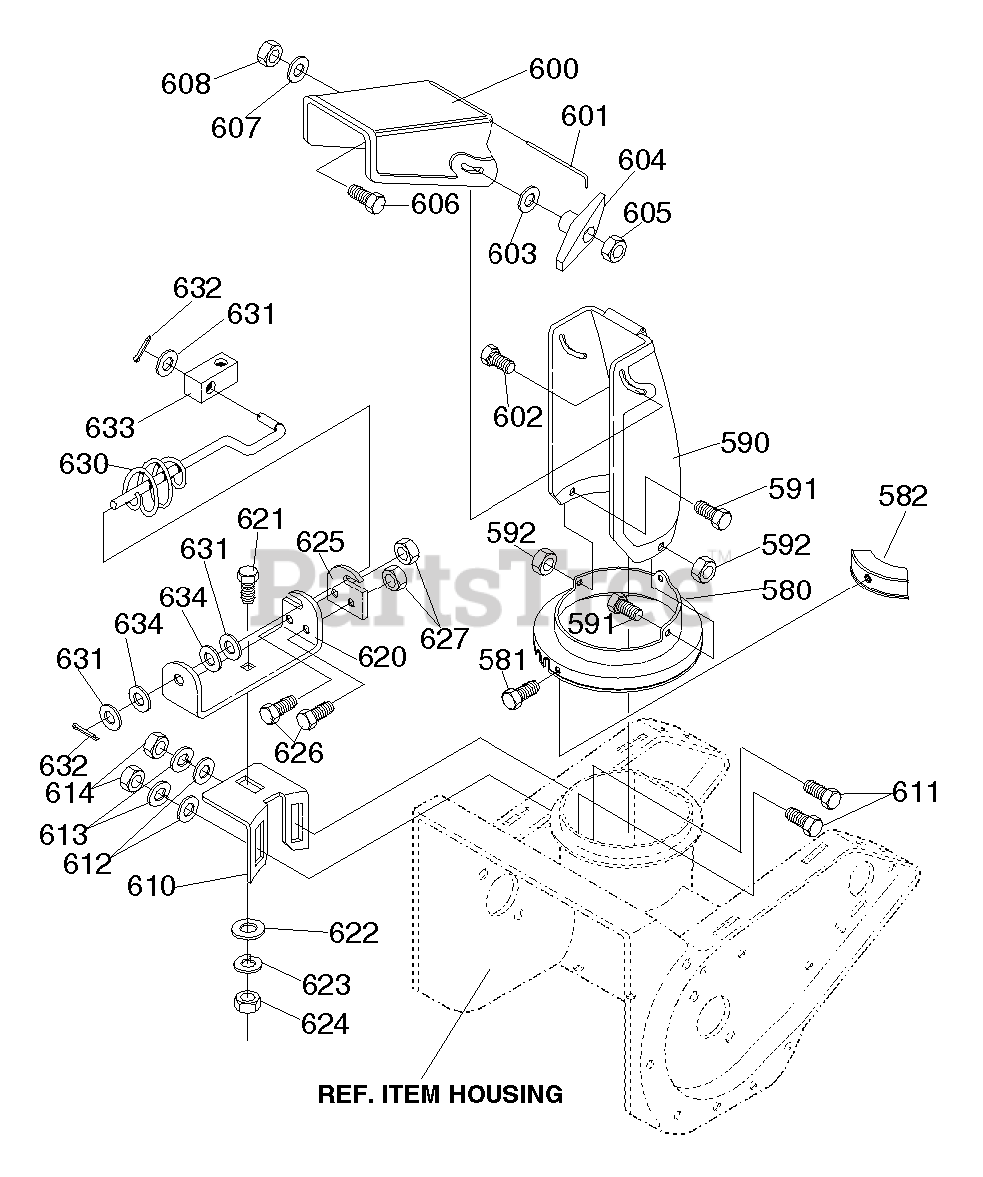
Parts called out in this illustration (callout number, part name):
580	RING, LOWER CHUTE
581	SCREW, 1/4-14X.63 HWATAP
582	CLIP, CHUTE RING PLASTIC
590	LOWER CHUTE
591	SCREW, 1/4-20X .50 HHC
592	NUT 1/4-20
600	CHUTE, UPR SRS W/O HDLE
601	HINGE WIRE
603	WASHER, FLAT .344X .69X.
604	KNOB, W/NUT
605	NUT, 5/16-18 REGHEX
606	SCREW, 5/16-18X.75
607	WASHER, FLAT .344X .69X.
608	NUT, 5/16-18 REGHEXCTRLK
610	MP BRACKET, WORM ADJ
612	WASHER, FLAT .344X .69X.
613	WASHER, HVSPTLK .328X.60X
614	NUT, 5/16-18 REGHEX
620	MP BRACKET, CHUTE ROD HOLDER
622	WASHER, FLAT .344X .69X.
623	WASHER, HVSPTLK .328X.60X
624	NUT, 5/16-18 REGHEX
625	PLATE, CHUTE ROD
626	SCREW, 1/4-20X .50 HHC
627	NUT, 1/4-20 REGHEXCTRLK
630	ROD, ASSY CHUTE LWR
631	WASHER, FLAT .40X.75X.025
632	PIN, COTTER .090/.086X.75
633	BLOCK, PIVOT PLASTIC
